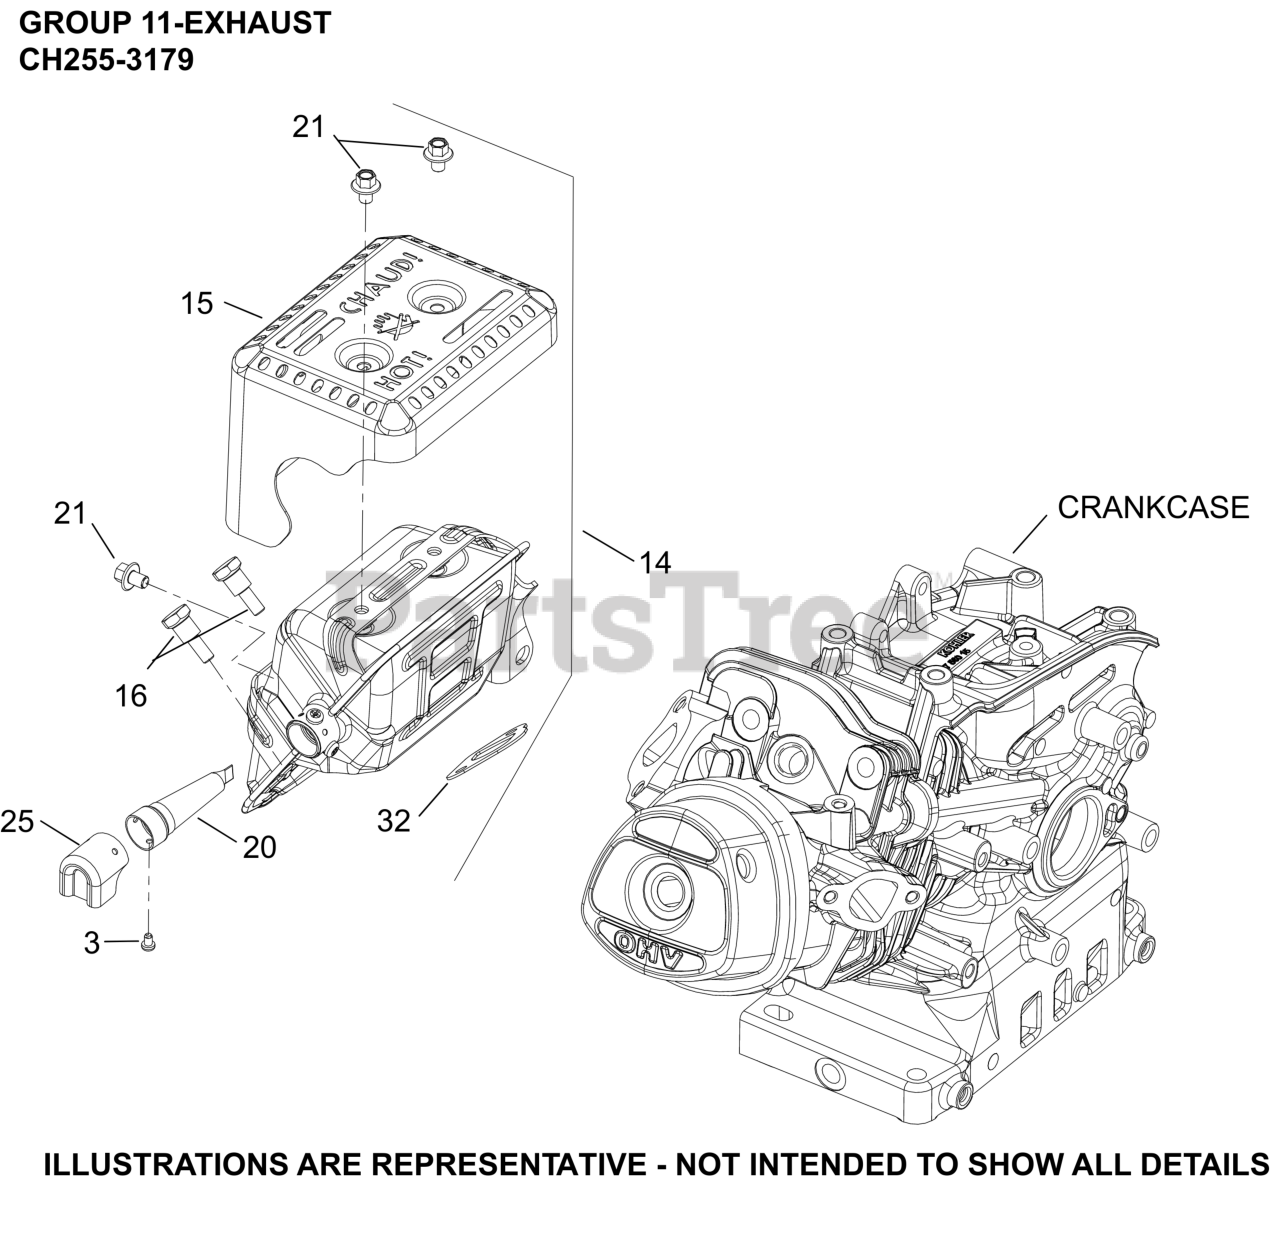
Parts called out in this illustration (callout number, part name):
3	SCREW, SPARK ARRESTOR
14	MUFFLER, ASSEMBLY
15	KIT, MUFFLER GUARD
16	SCREW, SHOULDER
20	SPARK ARRESTOR, ASSEMBLY
21	SCREW, M6 X 8 HEX FLANGE HEAD
25	KIT, DEFLECTOR & SCREWS
32	GASKET, MUFFLER
